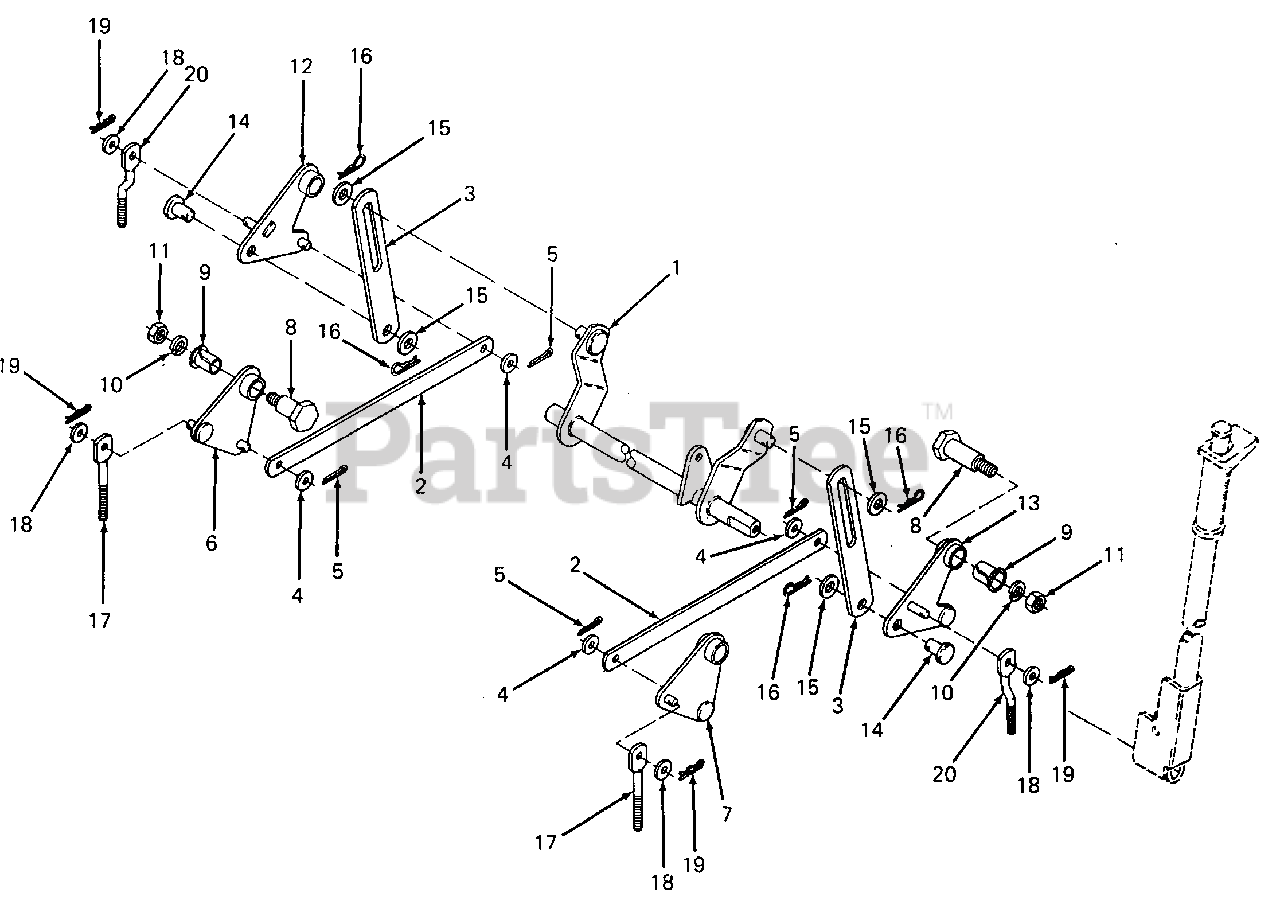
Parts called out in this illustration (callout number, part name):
1	Shaft Assy, Lift
3	Link, Lift
4	Washer, Flat, .406 X 1.0 X .030 Thk
5	Pin, Cotter, 1/8 X 3/4 Lg
6	Cam Assy, Rear Lift - LH
7	Cam Assy, Rear Lift - RH
8	Screw, Shoulder, .625 X .960
9	Bearing, Flanged Nyliner
10	Washer, Lock, 3/8
11	Nut, Hex Center Lock, 3/8-16 GR5
12	Cam Assy, Front Lift - LH
14	Pin, Clevis, .50 Dia X .62 Lg
15	Washer, Flat, .510 X 1.0 X .06 Thk
16	Pin, Internal Cotter
17	Link, Rear Lift
18	Washer, Flat, .406 X .75 X .063 Thk
19	Pin, Internal Cotter
20	Link, Front Lift
